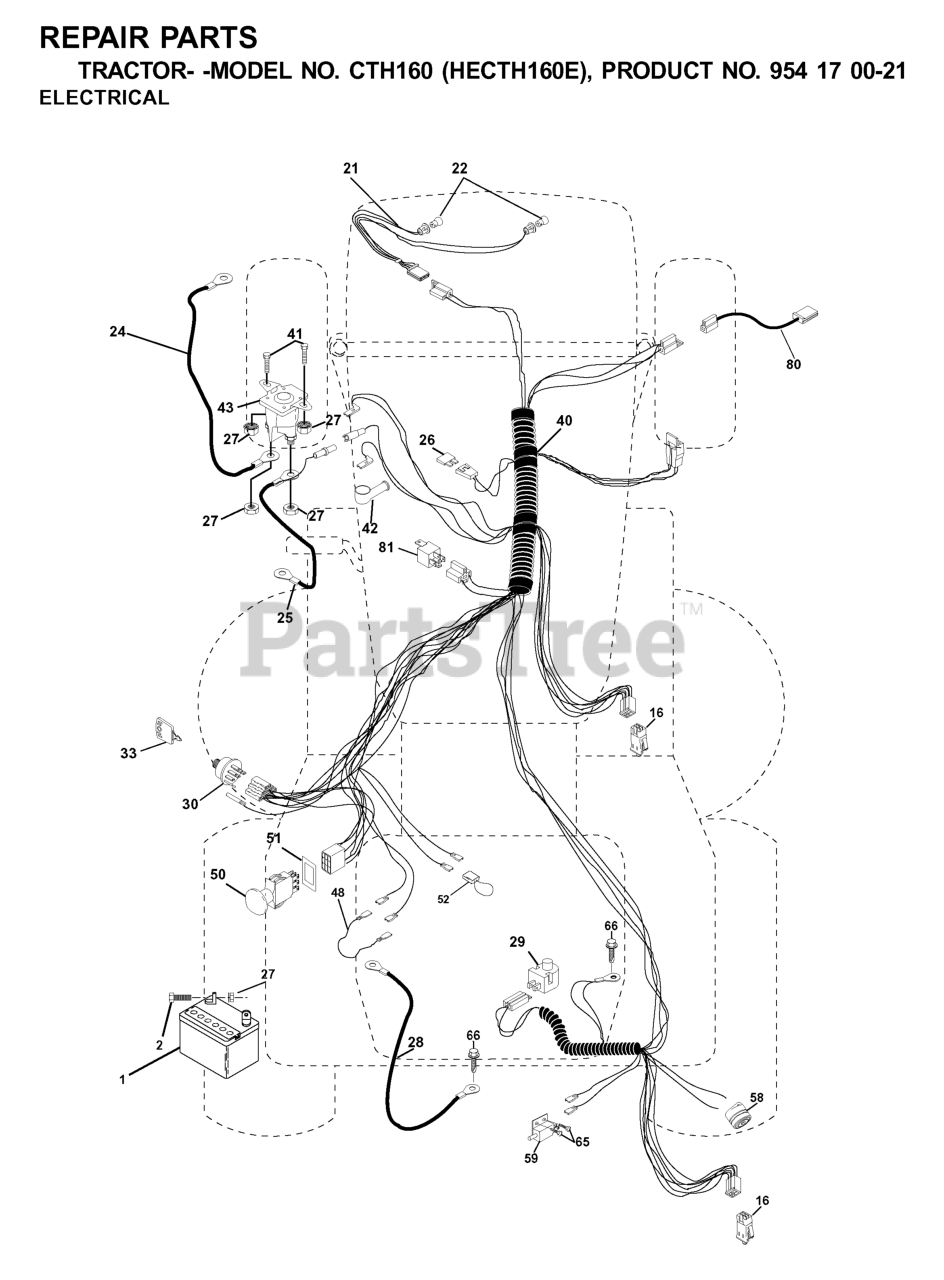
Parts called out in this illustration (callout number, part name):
1	BATTERY 12 VOLT 25 AMP
2	BOLT.HEX.1/4.X.3/4.DICHROMATE
16	SWITCH INTERLOCK
24	BATTERY CABLE GT
25	CABLE BATTERY
26	FUSE 20AMP
27	NUT
28	CABLE GROUND
29	PLUNGER SWITCH (COLOR:OLIVE)
30	IGNITION SWITCH
33	KEY MLD GEN DELTA
40	HARNESS.ING.CRD.ELECT
41	BOLT
42	TERMINAL COVER
43	REPL BY 532 1461-54
48	ADAPTER.AMMETER
50	RP.PTO.SWITCH.8 TERMINAL.BLACK
51	FRAME RETAINING RING
52	WIRE PROTECTION LOOP
58	BUZZER
65	Screw, Hex Wsh. Tap #10-16 x 1/2
80	HARNESS, CLUTCH
81	RELAY.ASSY.T
